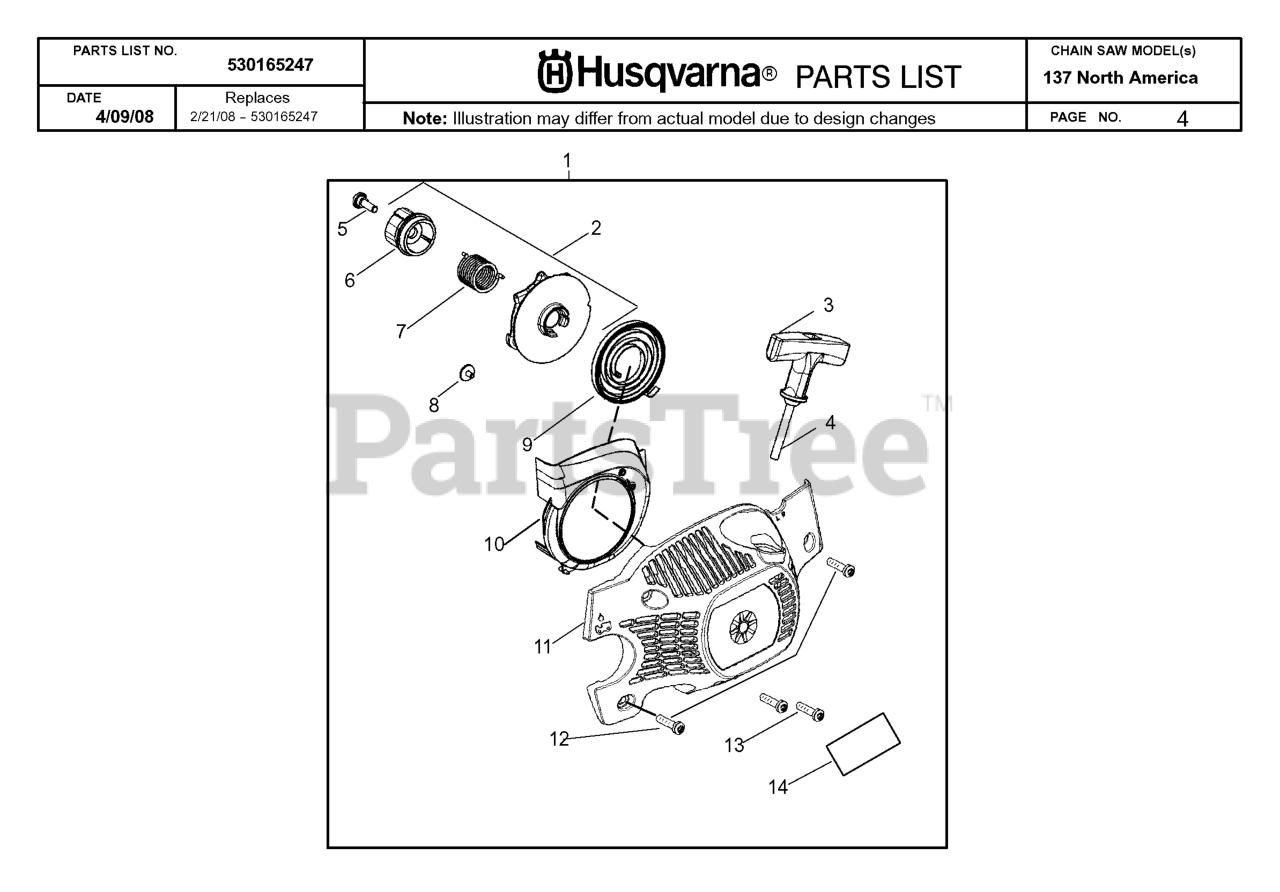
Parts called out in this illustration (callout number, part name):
1	KIT FAN HSG & STARTER EPS
2	KIT EPS STARTER
3	STARTER HANDLE GRAY
5	SCREW SHOULDER
6	HUB STARTER EPS
7	SPRING EPS
9	SPRING STARTER
10	BAFFLE AIR
11	HOUSING FAN W/ EYELET
13	SCREW,STRTR CVR 36/41
14	DECAL 137 STARTER
